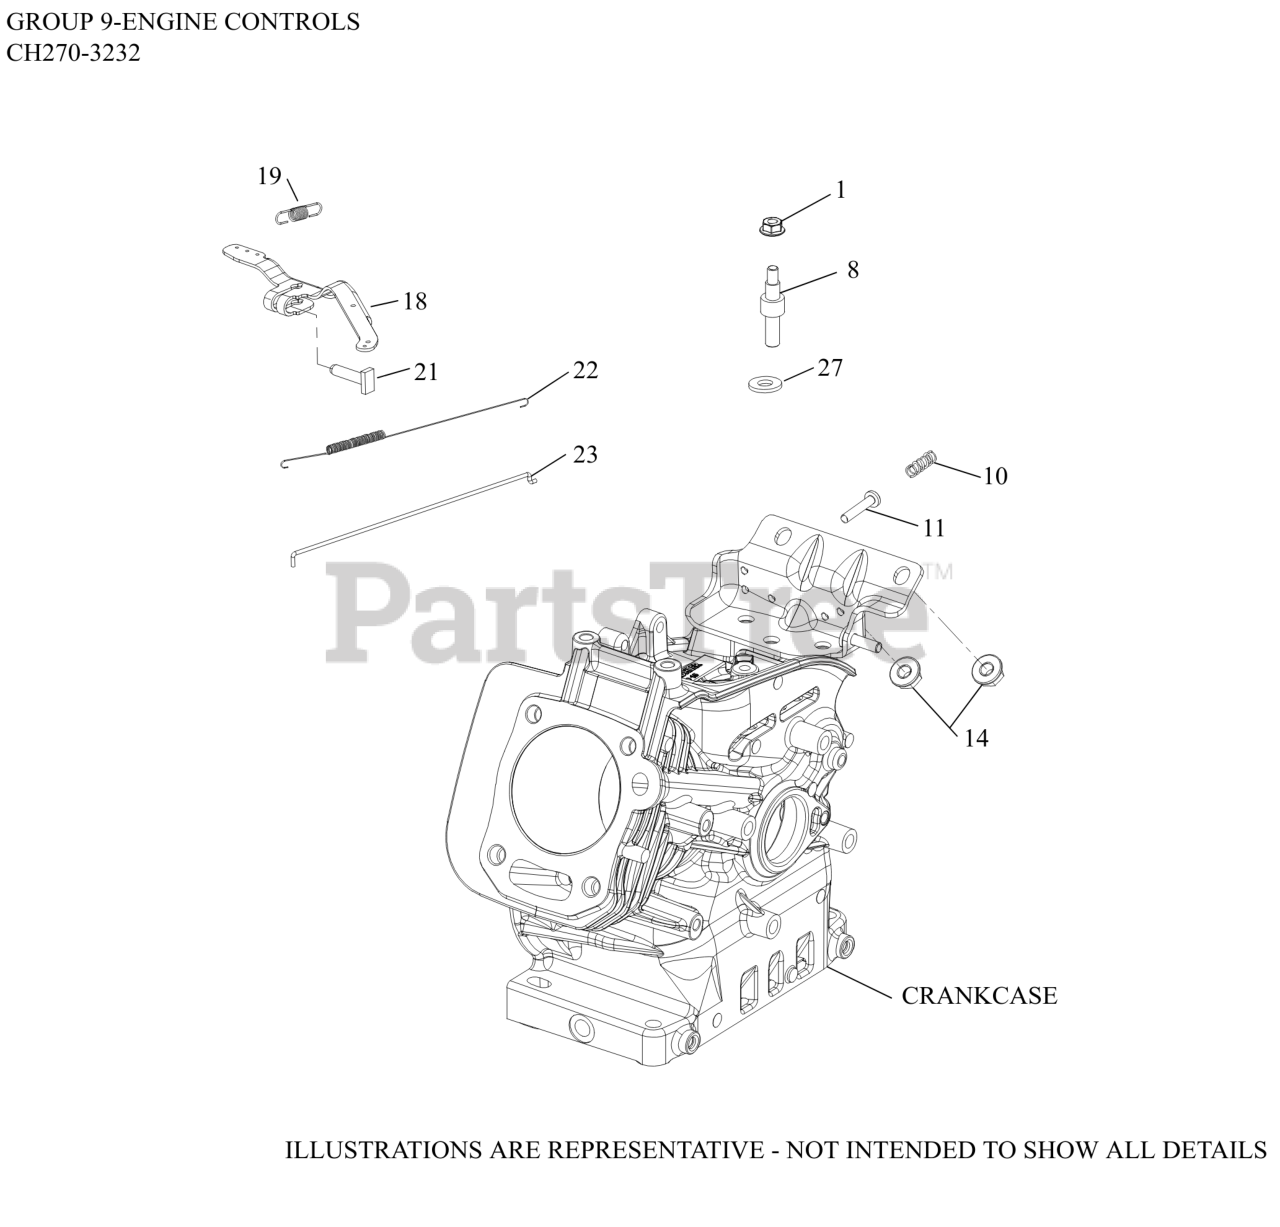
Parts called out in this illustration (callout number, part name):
1	NUT, HEX FLANGE LOCK (M6)
8	STUD, CONTROL LEVER
10	SPRING, COMPRESSION
11	SCREW, SPEED ADJUSTING
14	NUT, FLG M8X1.25
18	KIT, GOVERNOR LEVER
19	SPRING, GOVERNOR
21	SCREW, RECTANGLE HEAD (M6)
22	SPRING, LINKAGE
23	LINKAGE, GOVERNOR
